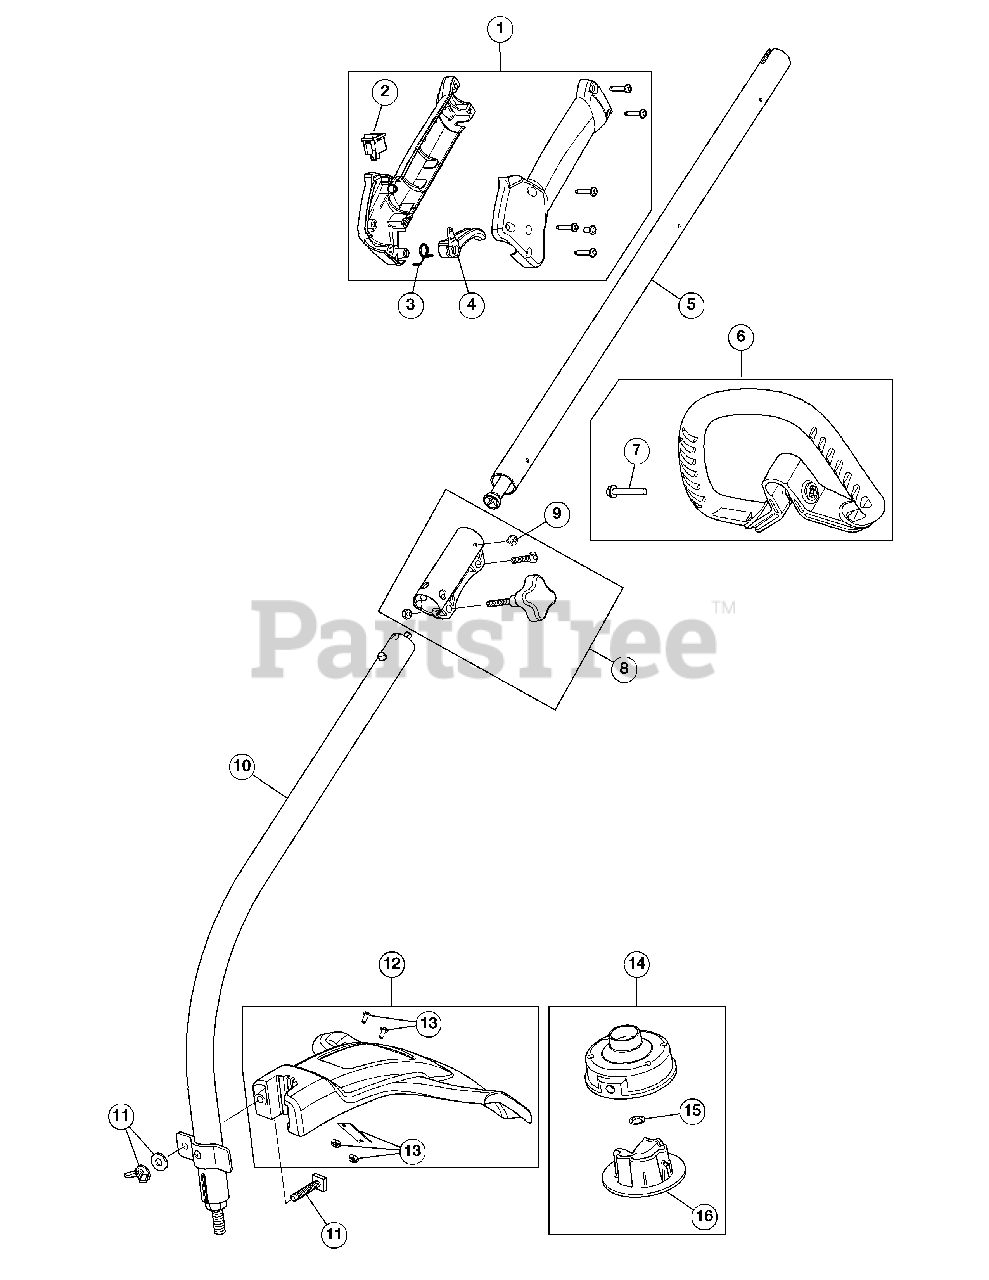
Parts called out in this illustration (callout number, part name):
1	Throttle Housing Assembly (Incl. 2 - 4)
2	Switch Assembly
3	Throttle Trigger Spring
4	Throttle Trigger
5	Upper Drive Shaft Assembly
6	D-Handle Assembly (Incl. 7)
8	Split Boom Coupler (Incl. 9)
9	Coupler Anti-Rotation Screw
10	Lower Drive Shaft Housing
11	Shield Mount Hardware
12	Shield Assembly (Incl. 13)
13	Blade Assembly
14	Cutting Head Assembly (Incl. 15 & 16)
15	Push Nut
16	Cutting Head Cap
